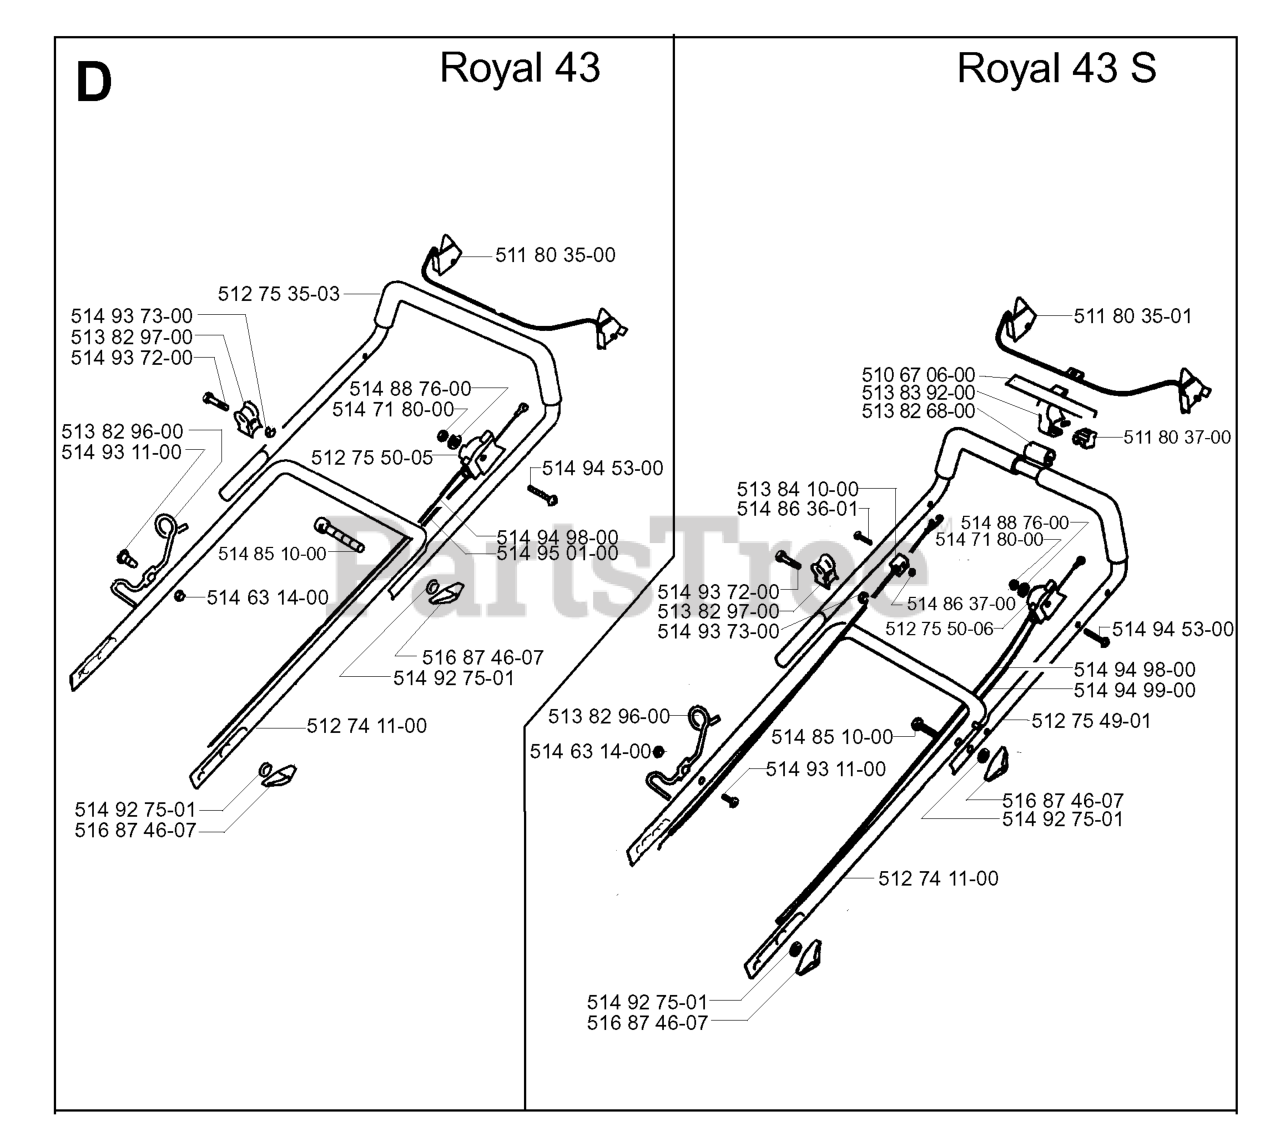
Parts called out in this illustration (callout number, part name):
1	STARTER DEVICE CPL
2	SCREW IHSCFT PW5.5X16 8.8 ZN/
4	STARTER PULLEY
7	RECOIL SPRING
8	STARTER ROPE
9	STARTER HANDLE
11	SCREW
12	STARTER HOUSING
13	AIR CONDUCTOR
14	DECAL
